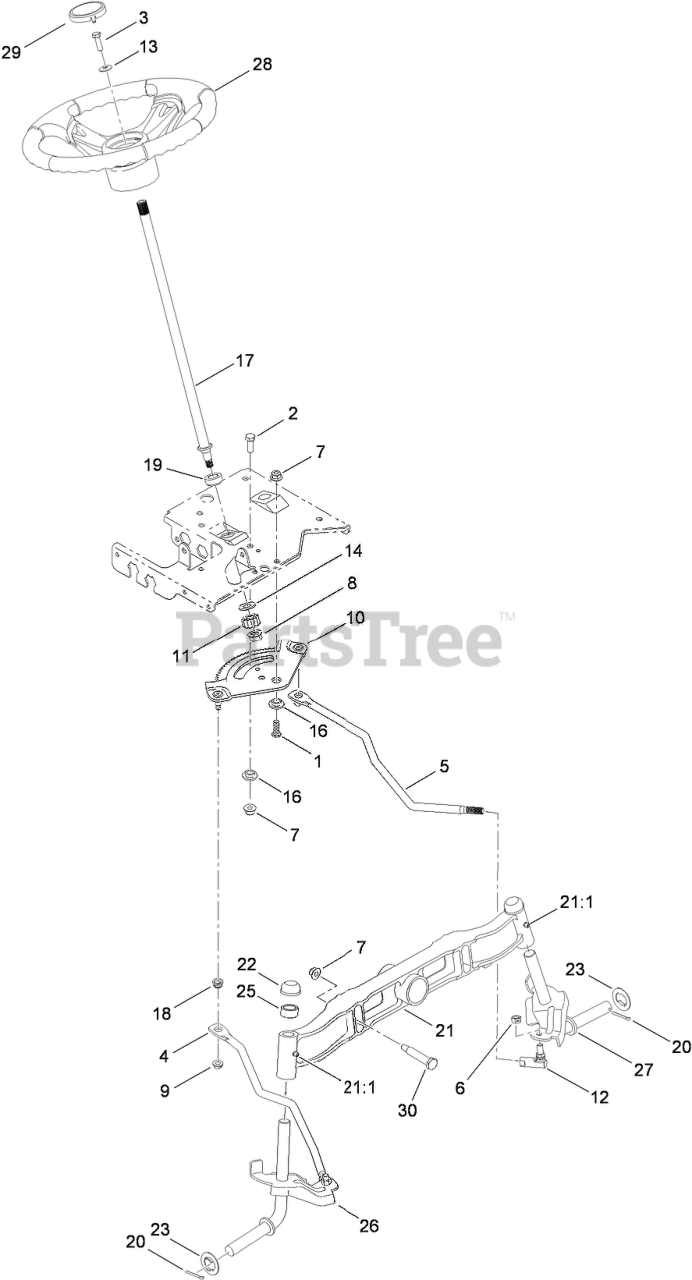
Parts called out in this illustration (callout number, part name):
1	SCREW-HH
2	SCREW-HH
3	SCREW-HH
4	LINK-DRAG, RH
5	LINK-DRAG, LH
6	NUT-HEX, LOCK
7	NUT-LOCK, FLANGE
8	NUT-LOCK, FLANGE
9	NUT-LOCK, FLANGE
10	GEAR-STEERING
11	GEAR-PINION, STEERING
12	BALL JOINT ASM
13	WASHER-FLAT
14	WASHER-FLAT
16	SPACER-SHOULDER
17	SHAFT-STEERING
18	BUSHING
19	BEARING-FLANGE, HEX
20	PIN-COTTER
21	PIVOT-AXLE, CAST IRON
21:1	FITTING-GREASE
23	WASHER-FLAT
25	SPACER
26	RH AXLE ASM
27	LH AXLE ASM
28	3 SPOKE WHEEL STEERING ASM
29	CAP-WHEEL, STEERING
30	BOLT-SHOULDER
